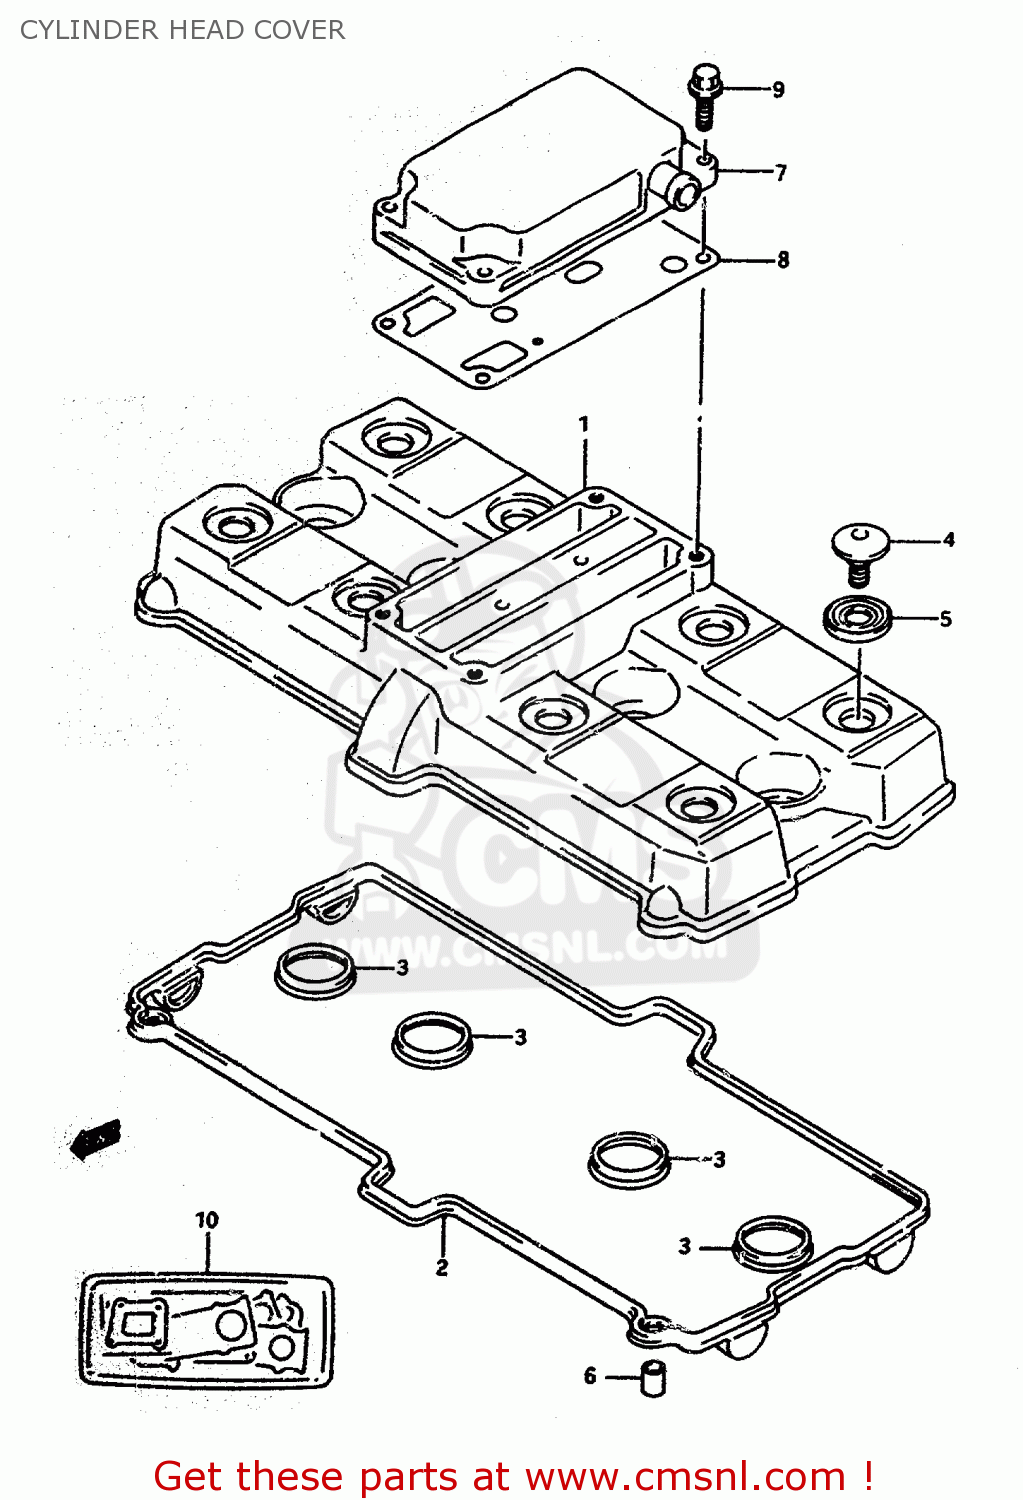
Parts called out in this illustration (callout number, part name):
1	COVER,CYLINDER HEAD
2	GASKET,CYL HEAD COVER NO.1
3	GASKET,CYL HEAD COVER NO.2
4	BOLT(7X17.5)
5	WASHER(10.6X25.5X2.3)
6	PIN(6.2X8X11)
7	COVER,BREATHER
8	GASKET,BREATHER COVER
9	BOLT
10	GASKET SET (NAS)
